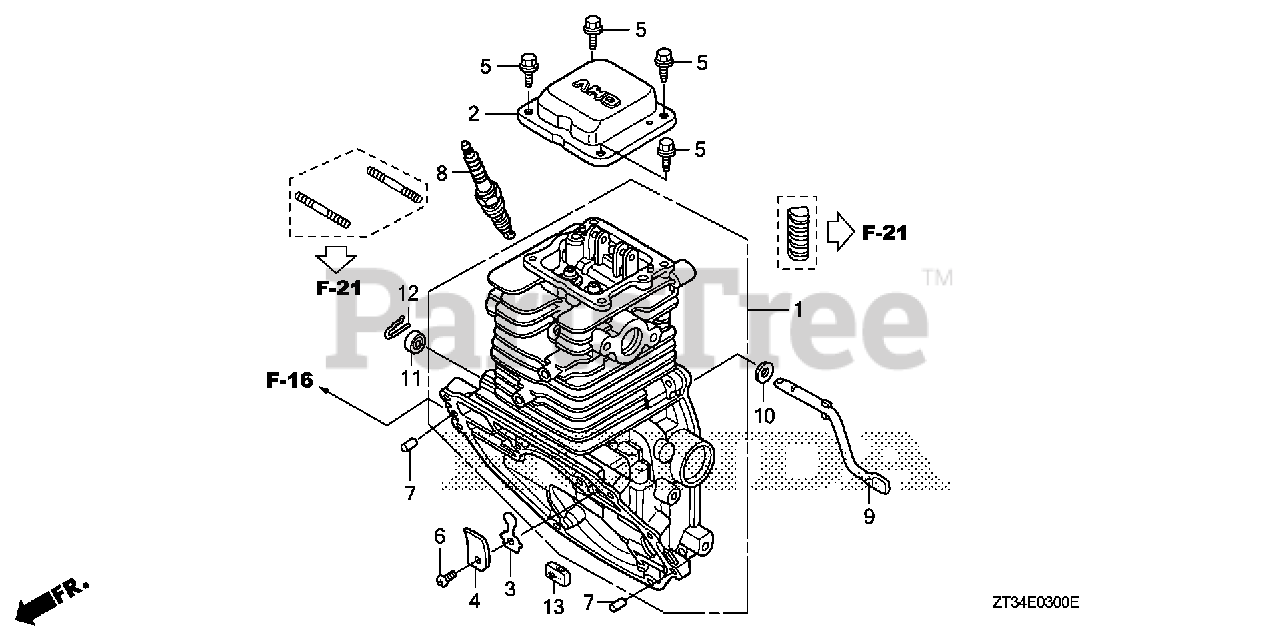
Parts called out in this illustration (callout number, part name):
1	CYLINDER
2	COVER, HEAD
3	VALVE, OIL OUTLET
4	PLATE, STOPPER
5	BOLT, FLANGE (5X12)
6	SCREW, PAN (3X5)
7	ROLLER (6X15)
8	SPARK PLUG (U14FSR-UB)
8	SPARK PLUG (CR4HSB)
8	SPARK PLUG (U16FSR-UB)
8	SPARK PLUG (CR5HSB)
9	SHAFT, GOVERNOR ARM
10	WASHER (5.2X9)
11	OIL SEAL (5X11X5)
12	PIN, LOCK (6MM)
13	FILTER, BREATHER
